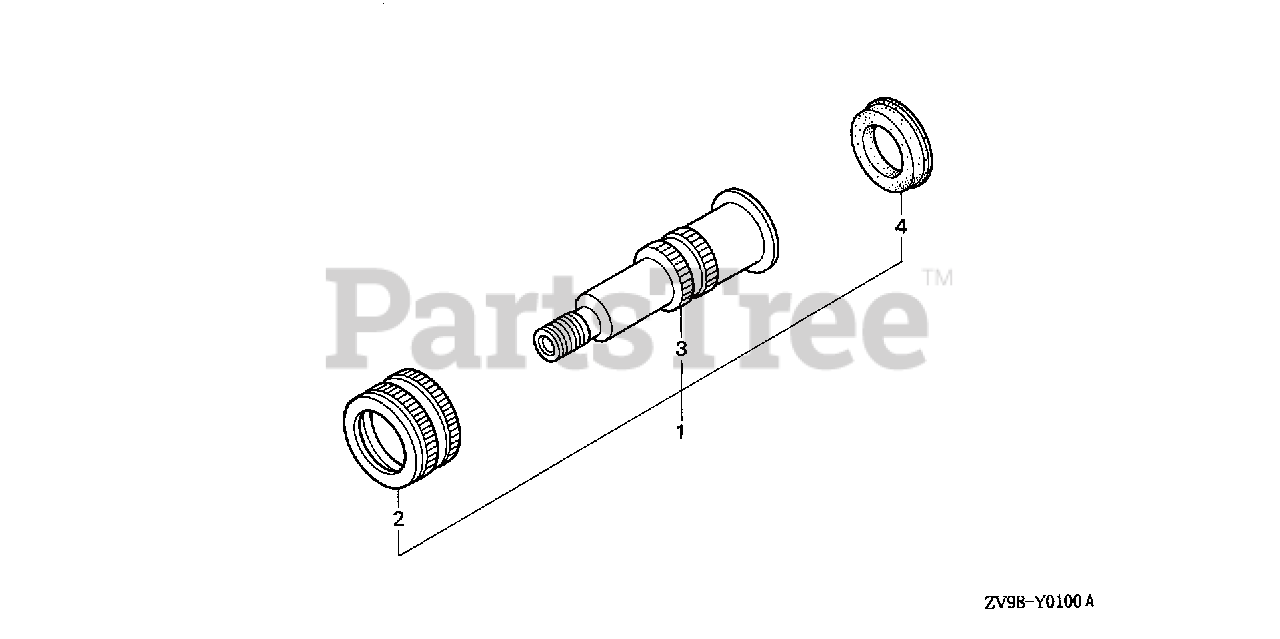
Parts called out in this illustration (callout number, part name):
1	JOINT KIT, WATER HOSE
2	NUT, WATER MOUTH
3	JOINT, WATER HOSE
4	SEAT, WATER MOUTH
